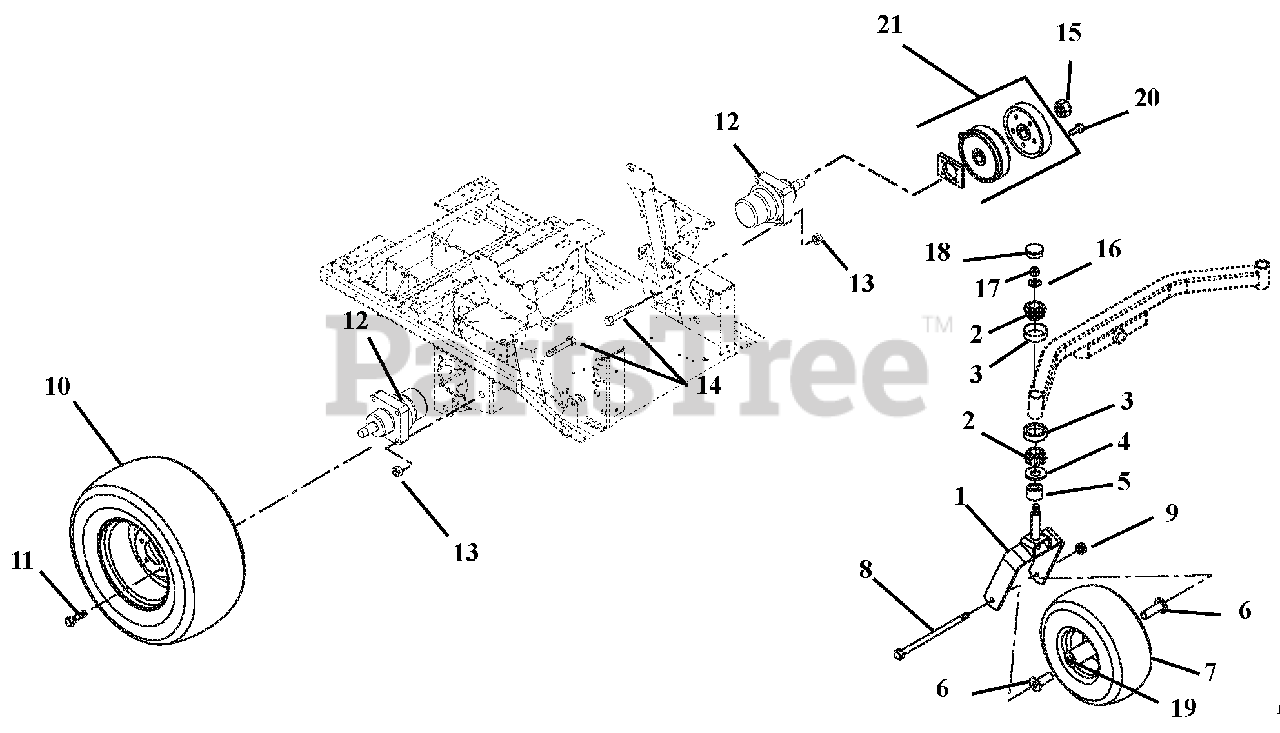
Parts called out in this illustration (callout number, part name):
1	Fork, Front
2	Bearing, Cone w/ Grease
3	Bearing, Cup 1.980 x .420
4	Bearing Seal 1.5 x 2 x .18
5	Spacer, PM, 1.03 I.D. x 1.5 O.D. x .375
6	Spacer, Wheel
7	Wheel/Tire Assembly
8	Bolt, Hex .50-13 x 9.00 Grade 5
9	Nut, Locking Center .50-13
10	Tire/Wheel Assembly 24 x 12-12
11	Bolt, Lug .50-20 x 1.38 Grade 8, 60 Degree
12	Hydraulic Wheel Motor (Includes item 15)
13	Nut, Locking Top Flange .50-13
14	Bolt, Wheel Motor .50-13 x 2.75
15	Nut , Lock Jam Patch (Included with 12)
16	Washer, Flat Steel 812 x 1.50 x .135
17	Nut, Jam Center-Lock .75-16
18	Cap, Dust
19	Bearing, 25mm I.D. x 52mm OD x 15mm
20	Bolt, Hex .31-18 x 1.5 Grade 5
21	Kit, Parking Brake Service
